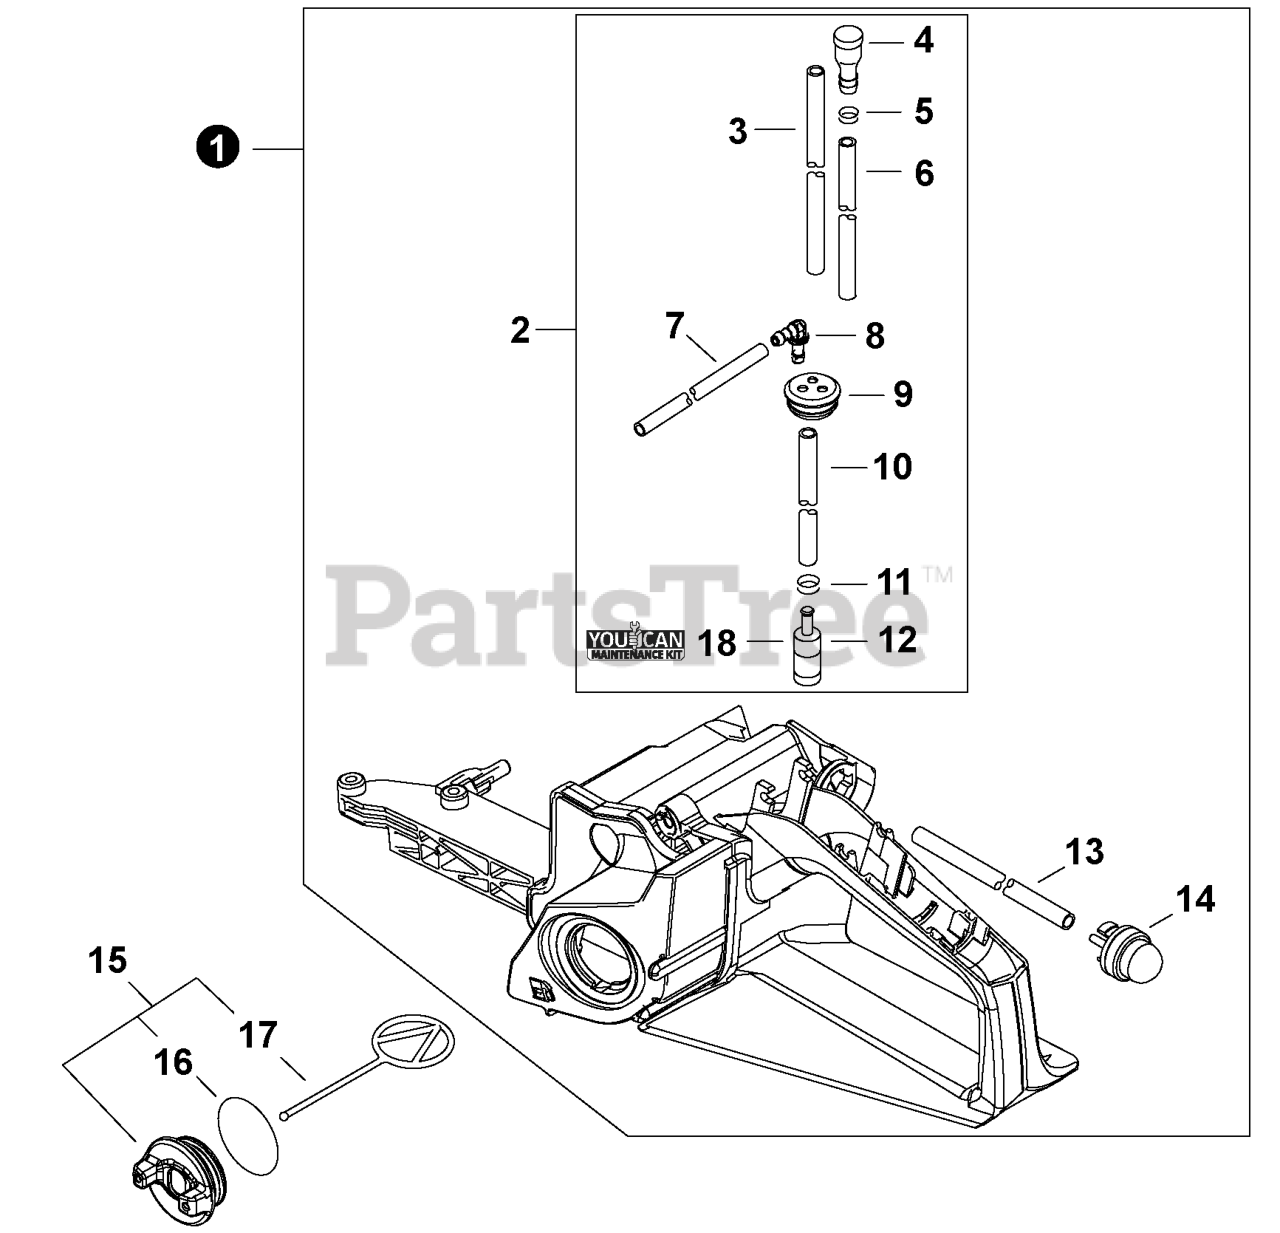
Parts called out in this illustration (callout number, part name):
1	HANDLE ASSY, REAR
2	FUEL SYSTEM KIT
3	PIPE, FUEL 2.4x5x75
4	VENT ASSY
5	CLIP 6.5 MM
6	PIPE 3x6x49
7	PIPE 3x5x160 EPA-KEP-002
8	CONNECTOR, PIPE
9	GROMMET, FUEL
10	PIPE, FUEL RETURN
12	FILTER, FUEL
13	PIPE, PURGE 2.4x5x140 BLACK
14	BULB, PURGE
15	CAP ASSY, FUEL
16	O-RING 29
17	CONNECTOR, CAP L= 60 MM
18	TUNE-UP KIT - YOUCANT
